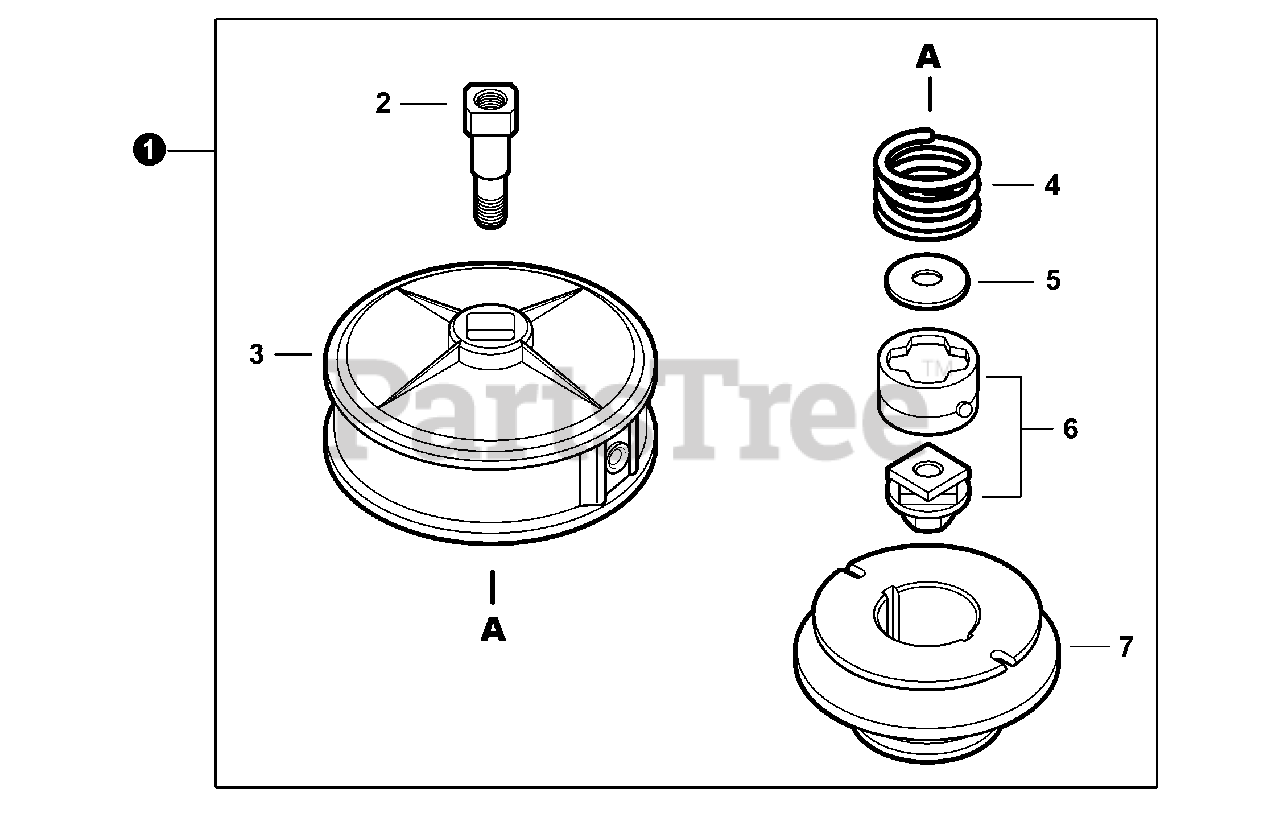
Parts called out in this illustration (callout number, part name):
1	TRIMMER HEAD, SRM ECHOMATIC®
2	STUD, ARBOR M10×1.25 LH
3	HOUSING, SPOOL
4	SPRING
5	WASHER
6	CAM ASSY
7	SPOOL
